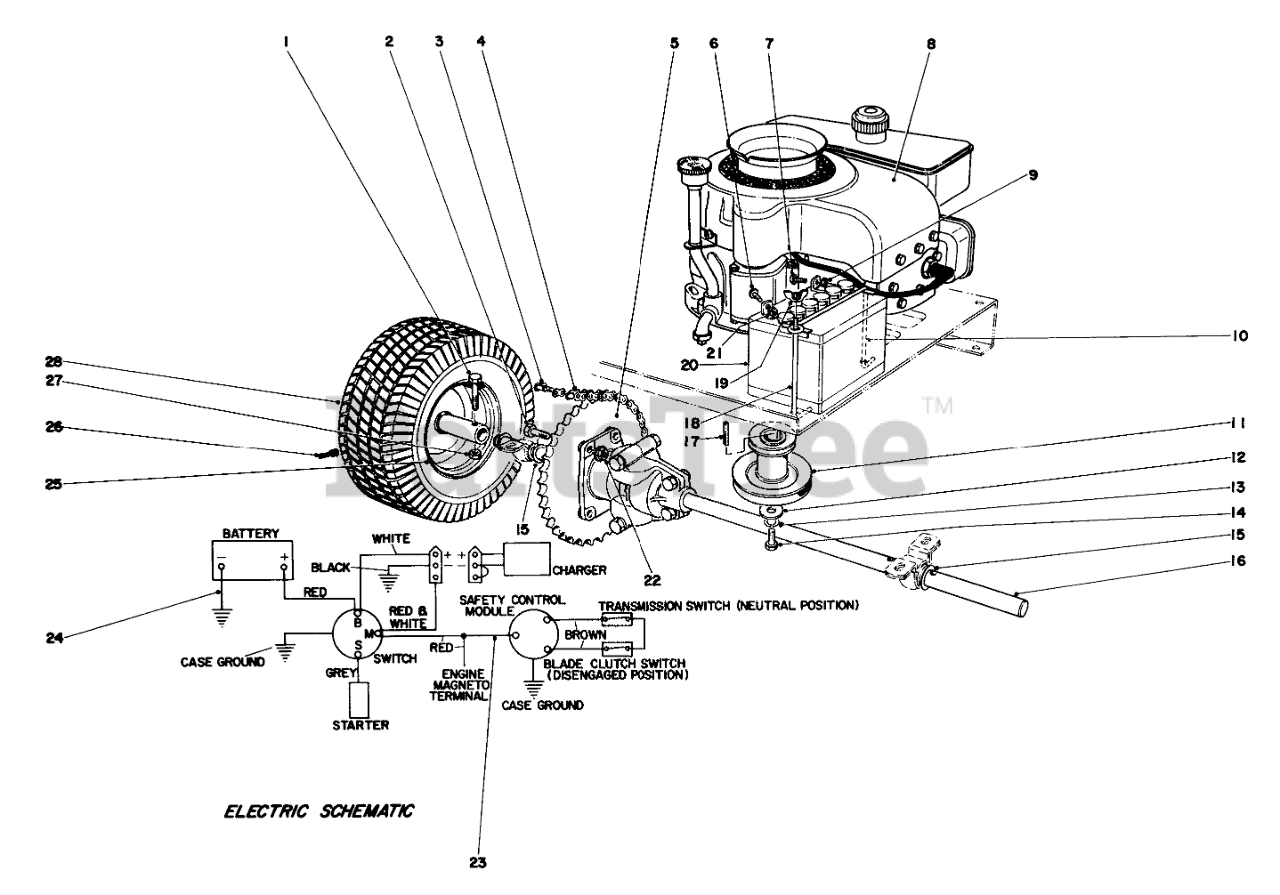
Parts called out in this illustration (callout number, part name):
1	SCREW-HH
2	SCREW-HH
3	LINK-CONNECTING
4	Chain
5	Sprocket
6	SCREW-HH
7	SCREW-HH
8	Engine
9	NUT-HEX
10	Battery Clamp
11	Pulley
12	Washer
13	WASHER-LOCK
14	SCREW-HH
15	WASHER
16	Differential
18	ROD-SUPPORT, BATTERY
19	NUT-WING SPECL
20	Battery
21	NUT-HEX
22	NUT-LOCK, CONE
23	Wiring Harness
24	ENG-GROUND WIRE ASM
26	STEM-VALVE
27	NUT-LOCK, CONE
28	Tire
